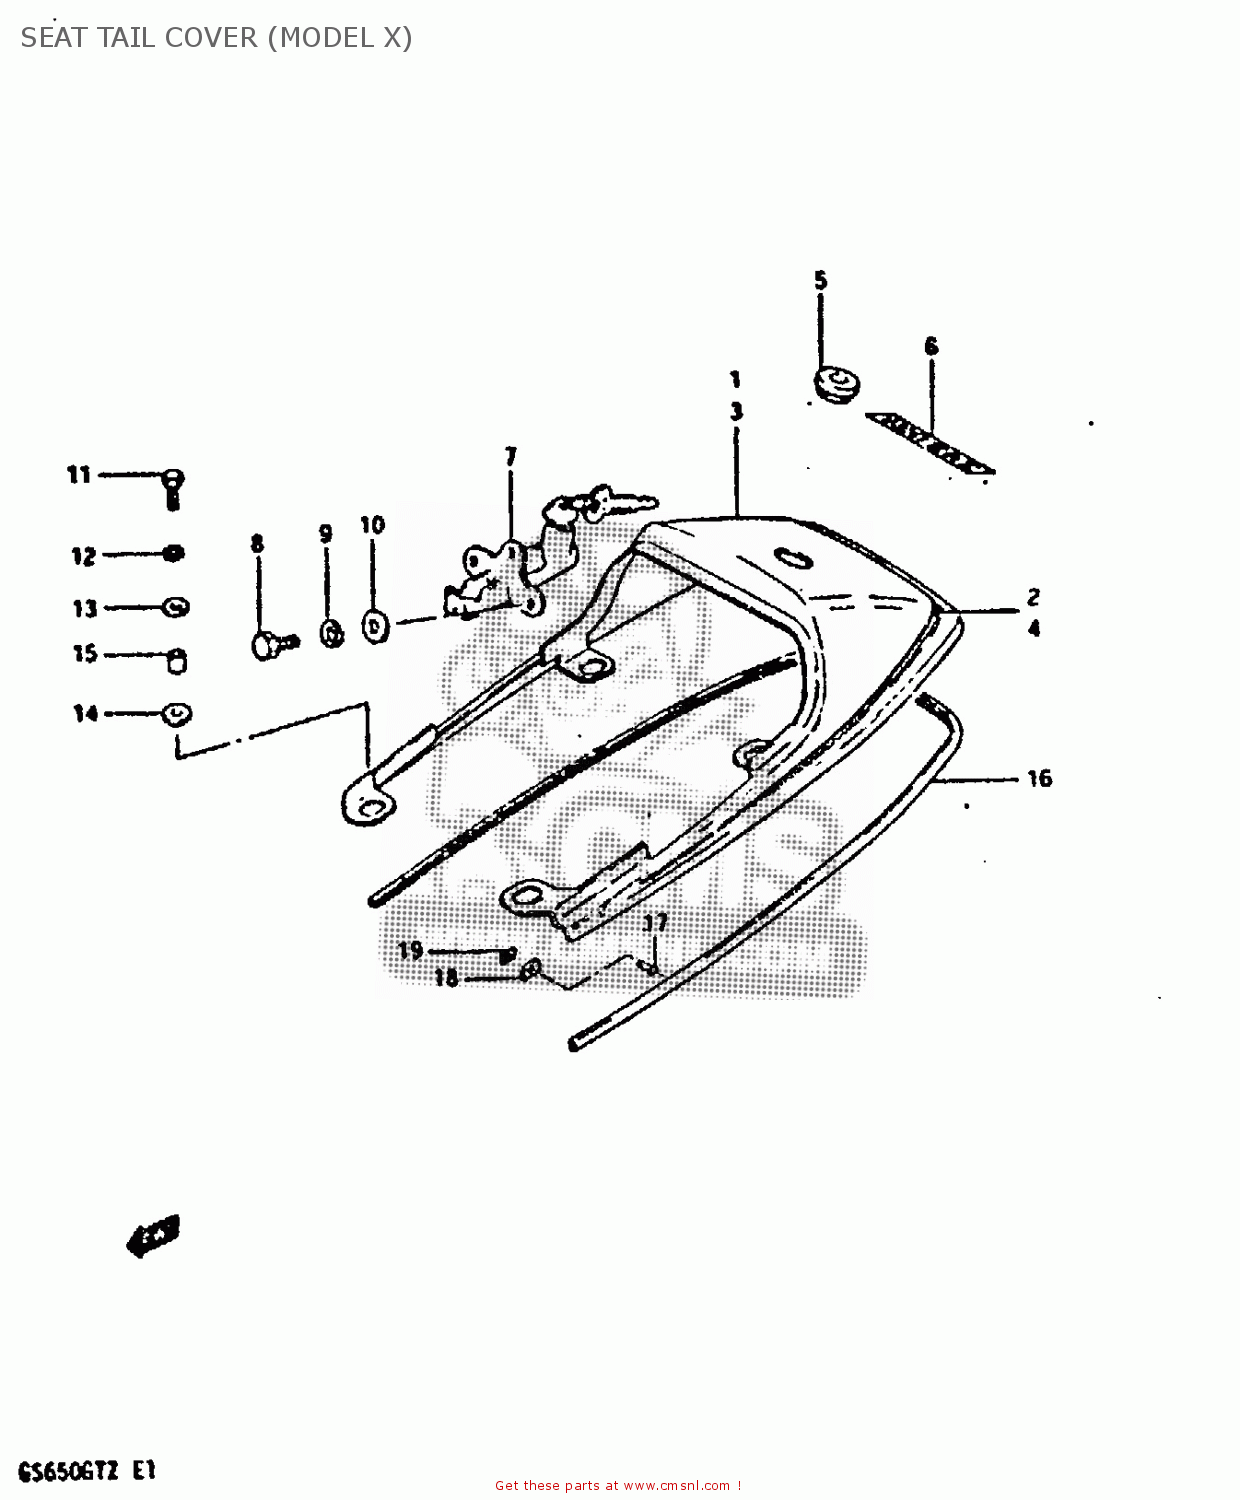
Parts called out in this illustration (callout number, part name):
1	COVER ASSEMBLY,SEAT TAIL
2	TAPE SET,BOX SEAT TAIL
3	COVER, SEAT TAIL (RED)
4	TAPE SET,BOX SEAT TAIL
5	GROMMET,SEAT LOCK HOLE
6	EMBLEM (GOLD/BLACK)
7	LOCK SET,SEAT
8	BOLT
9	LOCK WASHER
10	WASHER
11	BOLT
12	LOCK WASHER
13	WASHER(6,5X22X1.6)
14	CUSHION
15	SPACER(6.5X10.5X12)
16	MOLDING,SEAT TAIL COVER
17	RIVET
18	CUSHION,SEAT TAIL
19	NUT
